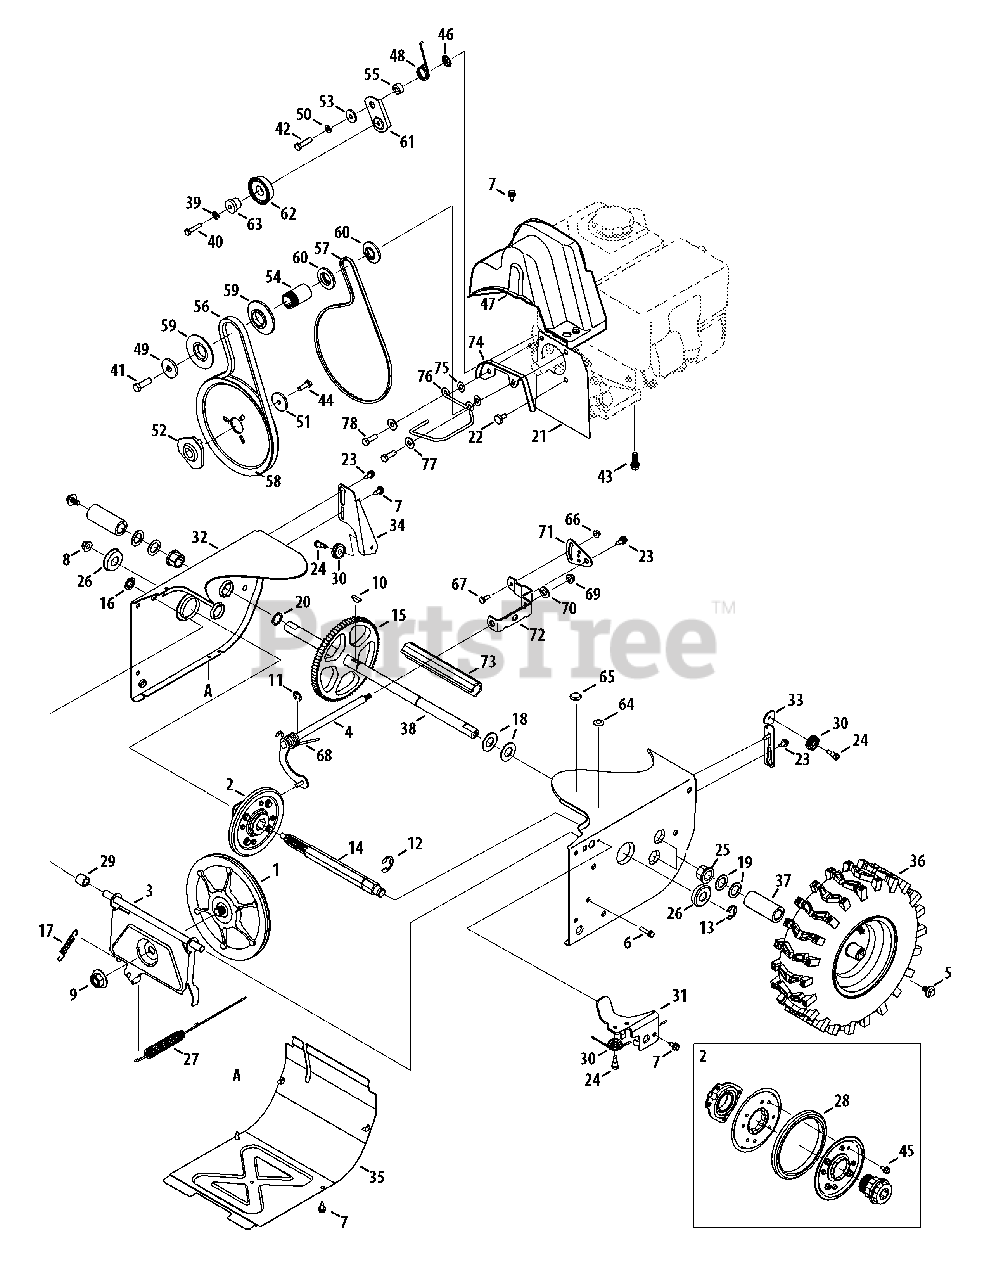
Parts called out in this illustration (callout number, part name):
1	Disc Assembly, Friction Wheel
2	Friction Wheel Assembly, 5.5 OD
3	Support Bracket, Friction Wheel
4	Shift Assembly, Rod
5	Screw, 5/16-24, .750, Gr5
6	Screw, 1/4-20, 1.000
7	Screw, 1/4-20 x .625
8	Nut, Flange Lock, 3/8-16, Nylon
9	Nut, Flange, 5/8-18
10	Key, Hi Pro, 3/16 x 3/4 Dia.
11	E-ring, .500 Dia.
12	E-ring, Retaining, .875 Dia.
13	E-ring, .750 Dia.
14	Hex Shaft, .8125, 7-Tooth
15	Gear, 80-Tooth
16	Speed Nut, .500
17	Extension Spring
18	Washer, Flat, .760 x 1.490 x .060
19	Washer, Flat, .793 x 1.24 x .060
20	Washer, Flat, .75 x 1.00 x .060
21	Plate, Cover
22	Shoulder Screw
23	Screw, Shoulder, .37 x .105, 1/4-20
24	Screw, 1/4-28, .375
25	Bearing, Hex Flange x .75 ID
26	Bearing, Ball, 17 x 40 x 12
27	Clutch Cable, Wheel, 44.95"
28	Rubber, Friction Wheel, 5.5 OD
29	Spacer, .508 ID x .75 OD x .68
30	Roller, Cable
31	Front Guide Bracket, Auger Cable
32	Frame
33	Guide Bracket, Auger Cable
34	Guide Bracket, Drive Cable
35	Cover, Frame
36	LH Wheel Assembly
36	RH Wheel Assembly
37	Spacer, 1.25 x .75 x 3.0
38	Axle, .75 x 22"
39	Washer, Lock, 1/4
40	Hex Screw, 1/4-20, 1.25, Gr5
41	Hex Screw, 3/8-24, 1.25, Gr8
42	Hex Screw, 5/16-24, 1.25, Gr5
43	Screw, Sems, 3/8-16, 1.00
44	Hex Screw, 5/16-24, .875, Gr8
45	Screw, 5/16-18 x .750
46	Nut, Push-on, .25 Dia.
47	Cover, Belt
48	Spring, Torsion, .850 ID x .354
49	Washer, Flat, .45 x 1.5 x .172
50	Washer, Lock .3125
51	Washer, Flat, .34 x 1.50 x .150
52	Pulley, Adapter, .75 Dia.
53	Spacer, Shoulder, .317 x .50 x .102
54	Spacer, .875 ID x 1.185 OD
55	Spacer, .340 x .750 x .360
56	Belt, Auger Drive
57	Belt, Wheel Drive
58	Pulley, Auger Drive, 8.1 x .5
59	Pulley, Half, V x 2.600 OD
60	Pulley, Half, 3/8-V x 1.7160 OD
61	Idler Bracket, Wheel Drive
62	Idler Pulley Assembly
63	Spacer, Shoulder, .26 x .79 x .538
64	Plug, 3/8 ID
65	Plug, 1/2 ID
66	Nut, Flange Lock, 1/4-20, Nylon
67	Hex Screw, 1/4-20, .620, Gr5
68	Spring, Torsion, .750 ID x .968
69	Nut, Flange Lock, 5/16-18, Nylon
70	Wash., Flat, .469 x .875 x .105
71	Pivot Bracket, Speed Selector
72	Shift Bracket, Speed Selector
73	Spacer, Axle
74	Belt Cover
75	Washer, Flat, .330 x .687 x .030
76	Belt Guide
77	Flat Washer, .349 x .879 x .063
78	Screw, 5/16-24 x 1.00
